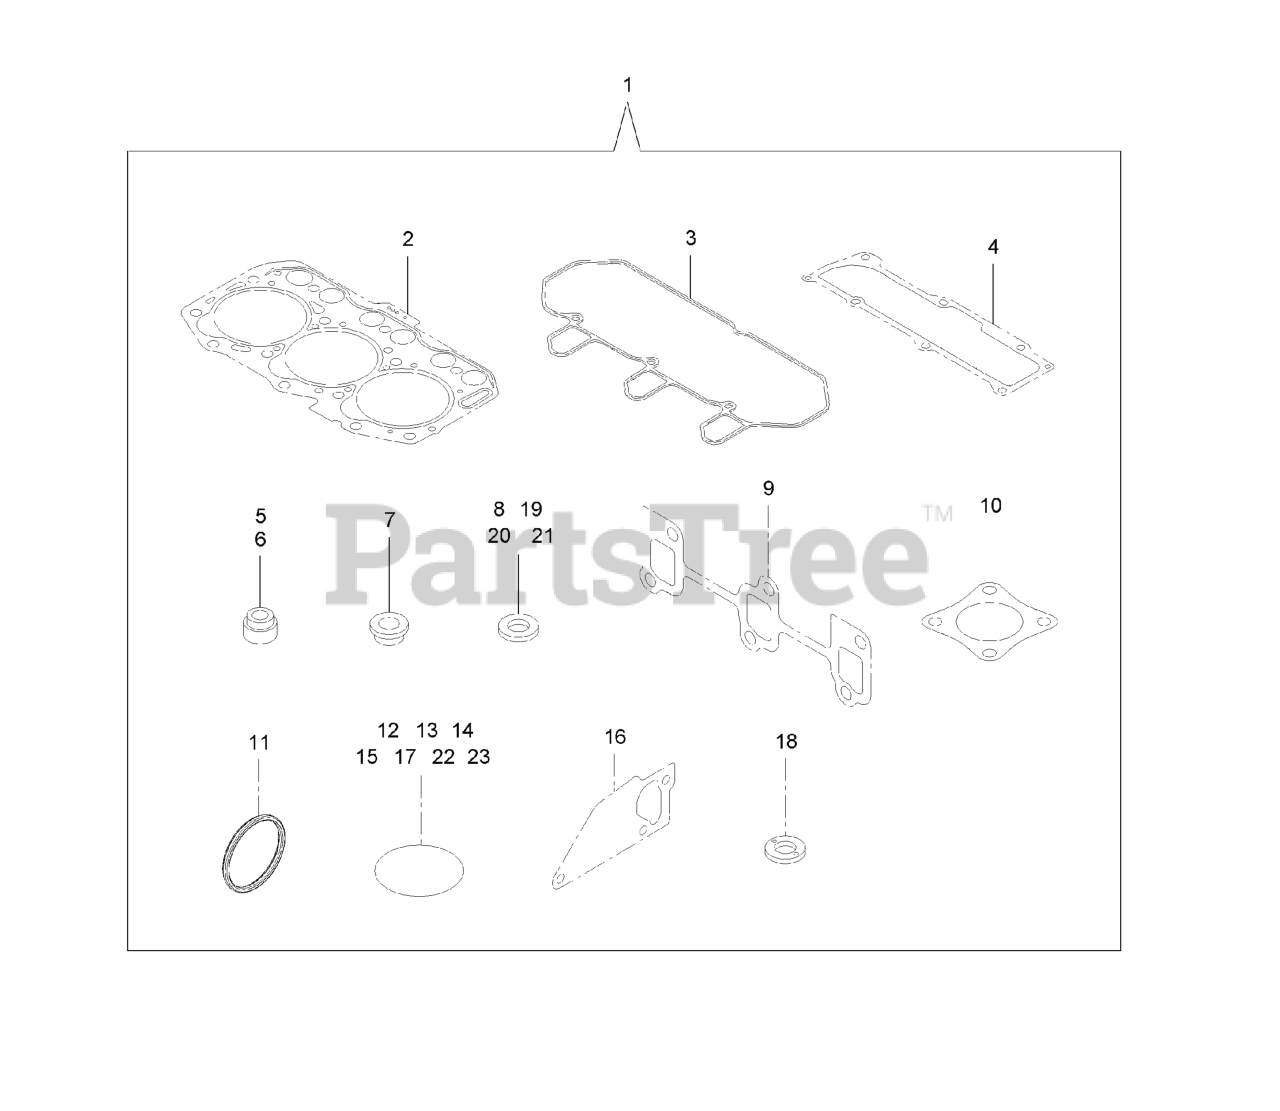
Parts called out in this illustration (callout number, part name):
1	GASKET KIT
2	GASKET SET-HEAD
3	GASKET-BONNET
5	SEAL-STEM, VALVE
6	SEAL-STEM, VALVE
7	PROTECTOR-NOZZLE
8	GASKET-NOZZLE
9	GASKET-EXH MANIFOLD
10	GASKET-SILENCER
11	GASKET-WASHER
16	GASKET-WATER PUMP
19	WASHER-SEAL
20	WASHER-SEAL
